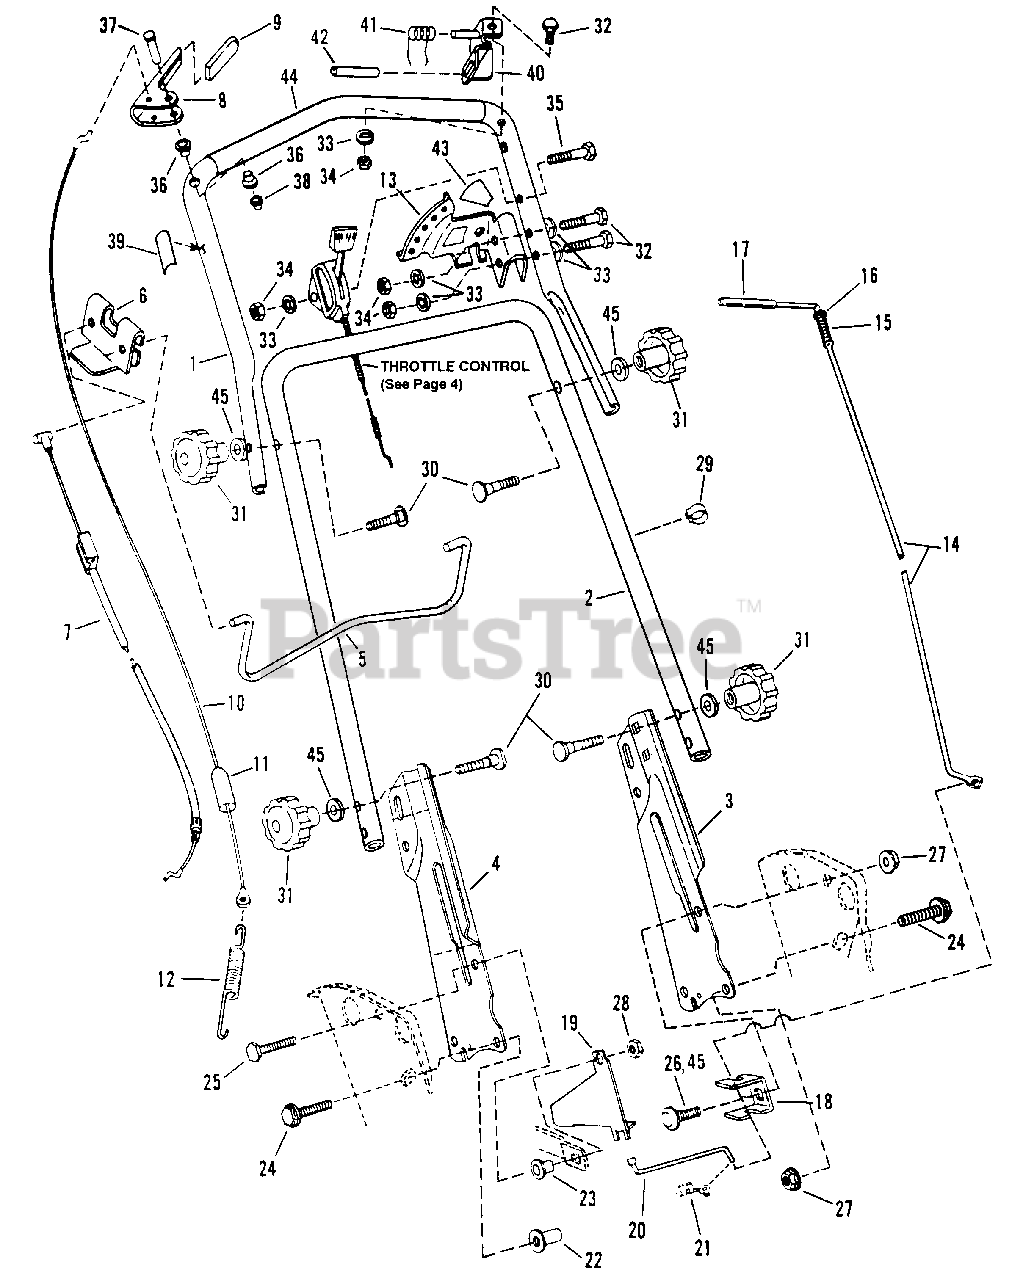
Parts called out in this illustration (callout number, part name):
1	HANDLE, Upper
2	HANDLE, Middle (15.5" Wide ID)
3	HANDLE, Lower Left Hand
4	HANDLE, Lower Right Hand
5	CONTROL, Blade
6	CLIP, Blade Control
7	CABLE, Blade Control
8	HANDLE, Wheel Drive
9	GRIP, Wheel Drive Handle
10	CABLE, Clutch Pull
11	COVER, Vinyl
12	SPRING, Clutch
13	SECTOR, Speed
14	LEVER, Speed Control
15	SPRING, Speed Control
16	WASHER, 3/8" Flat
17	GRIP, Speed Control Handle
18	ANCHOR, Speed Control
19	GUIDE, Lower V-Belt
20	ROD, Transfer
21	CLIP, Transfer Rod
22	TEE-NUT, 5/16-18
23	BUSHING, Differential
24	BOLT, 5/16-18x3/4 Flange Lock
25	CAPSCREW, 5/16-24 x 1
26	BOLT, 5/16-18x5/8 Carriage
27	NUT, 5/16-18 Hex Flange Lock
28	NUT, 5/16-24 Center Lock
29	CLIP, Cable/Wiring
30	SCREW, 5/16-18 x 2" Curved Head
31	KNOB, 5/16-18
32	CAPSCREW, 1/4-28 x 1-3/8
33	LOCKWASHER, 1/4 Internal Tooth
34	NUT, 1/4-20 Hex
35	CAPSCREW, 1/4-28 x 1-3/4
36	BUSHING
37	PIN, Clutch Handle
38	PUSH-NUT
39	DECAL, Blade Control
40	ASSEMBLY, Blade Control Bracket
41	SPRING, Blade Control
42	GRIP, Pivot
43	DECAL, Speed Sector
44	GRIP, Foam
45	LOCKWASHER, 5/16 Internal Tooth
